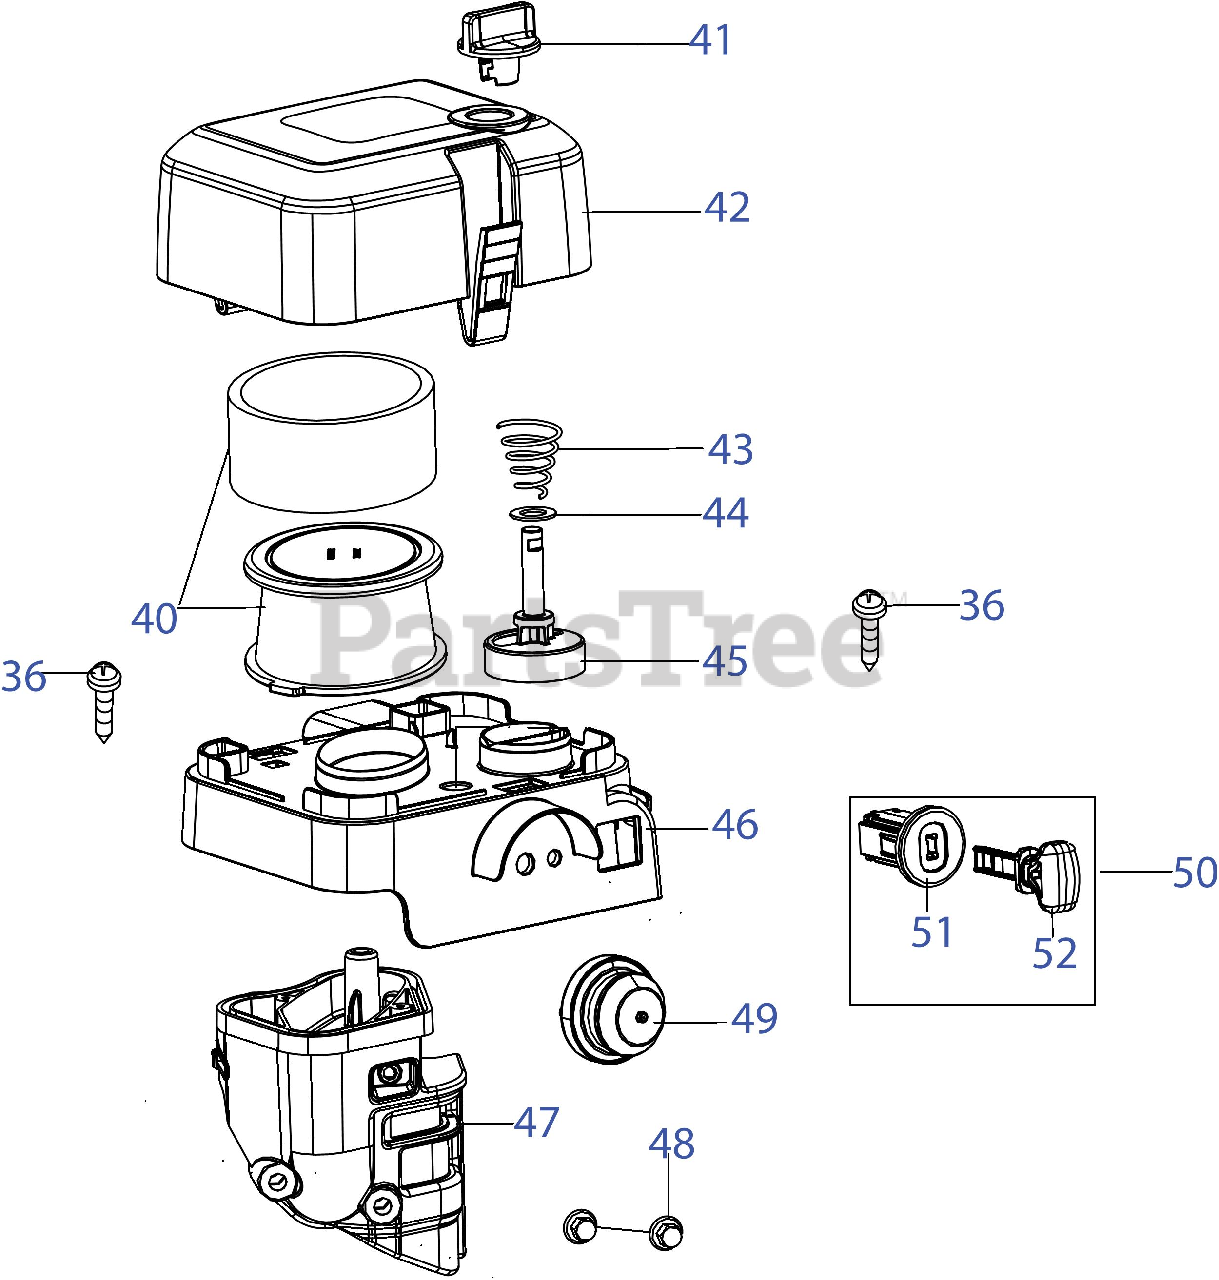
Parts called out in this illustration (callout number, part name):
36	Screw 4.2x20
40	Air Filter Element
42	Air Filter Cover
43	Taper Spring
44	Washer 9x1x16
45	The Air Filter Shaft
46	Silencer Plate
47	Air Filter Base
50	Engine Switch
51	Engine Switch Base
52	Engine Switch Key
